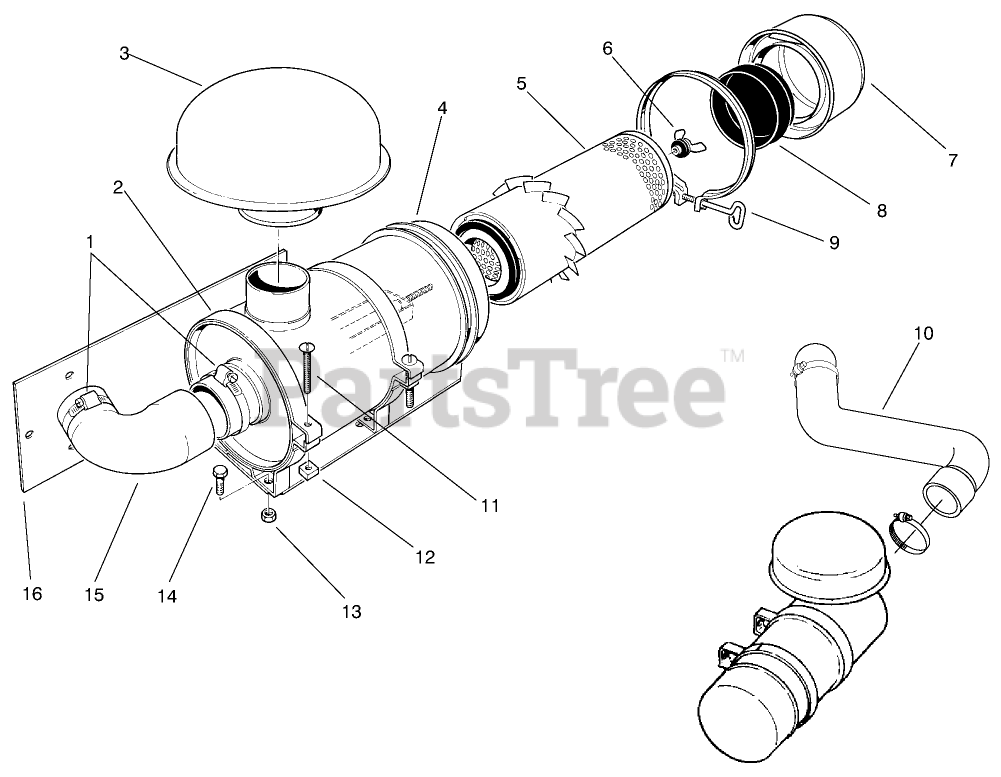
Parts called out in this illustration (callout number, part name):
1	CLAMP-HOSE
2	MTG BAND ASM
3	HOOD-INLET, AIR
4	Asm-Body
5	ELEMENT ASM
6	NUT ASM
7	CUP ASM
8	BAFFLE
9	CLAMP ASM
10	Hose-Air (Used on Proline 120 )
11	SCREW
12	NUT-SQUARE
13	NUT-LOCK, NI
14	SCREW-HH
15	Hose-Air (Used on Proline 117 & 118)
16	MTG BRACKET WA
